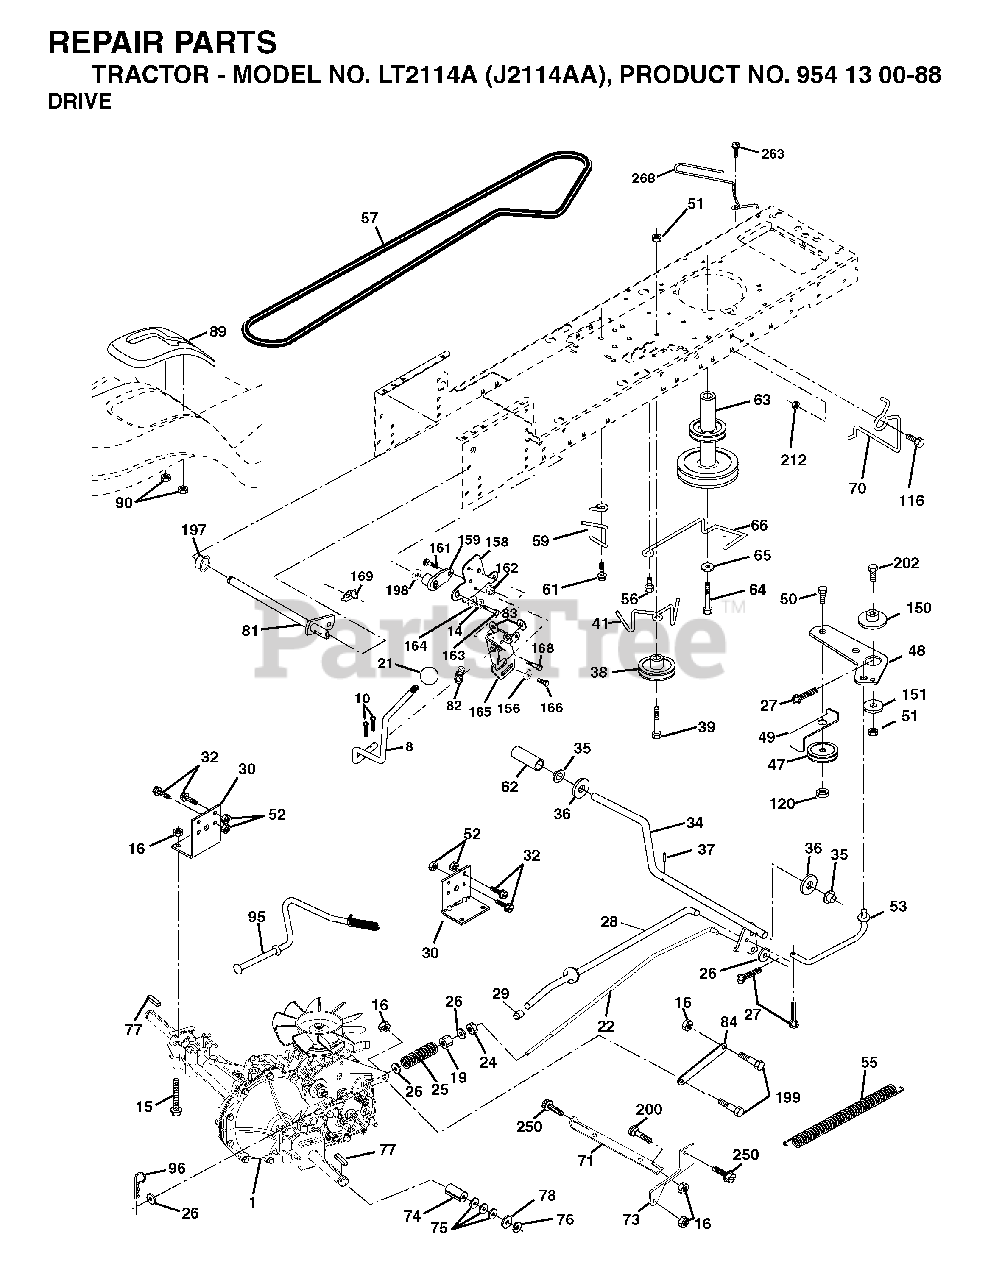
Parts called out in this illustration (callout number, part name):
8	ROD SHIFT FENDER ADJUST STLT
10	PIN COTTER
14	LOCKWASHER
15	BOLT HEX 5/16-18 GR 5
16	NUT.71038.31-18.HEX.NYLOCK
19	NUT
21	KNOB.DUCKHEAD.1/2
22	ROD BRAKE HYDRO
24	NUT
25	SPRING ROD LT
27	COTTER PIN
28	ROD, PARKING BRAKE
29	PLUNGER CAP
30	BRKT, MOUNT TRNSAXLE
32	BOLT
34	SHAFT, FOOT PEDAL
35	BEARING.NYLON
36	WASHER LT
37	DRIVE PIN
38	PULLEY IDLER COMPOSITE
39	BOLT
41	KEEPER, BELT IDLER
47	IDLER PULLEY
48	BELLCRANK, CLUTCH
49	RETAIN BELT
50	BOLT.3/8-16X1.50
51	LOCKNUT
52	LOCKNUT
53	LINK, CLUTCH LT
55	SPRING, RETURN LT
56	SCREW.3/8-16
57	DRIVE BELT, LTH & YTH TRACTORS
59	KEEPER, BELT CENTER
61	SCREW 3/8-16X.875
62	PEDAL COVER T
64	BOLT
65	LOCKWASHER
66	KEEPER BELT ENGINE
71	STRAP TORQUE LH HYDRO
73	STRAP TORQUE RH HYDRO
74	SPACER AXLE
76	E-RING LT
77	SQUARE KEY
81	SHAFT ASM CROSS TAPERED
82	SHIFT SPRING
83	WASHER
95	CONTROL ASM. BYPASS HYDRO
96	RETAINER M
103	NUT.HEX.1/2-20
116	BOLT D
120	NUT LOCK FLG 3/8-16 UNC
150	SPACER, RETAINER
151	WASHER 12/32X2X10GA
156	WASHER.SRRTD.5/16
158	BRACKET
159	HUB
161	BOLT
162	NUT.CROWNLOCK.1/4
165	RP BRACKET
168	BOLT.SHOULDER.5/16-18X
169	PLATE.FASTENING.CROSS.SHAFT
197	NYLINER SNAP 5/8" ID
198	WASHER.NYL.7/8IDX.105"HYD CR
199	BOLT SHOULDER 5/16-18 UNC
200	BOLT
202	BOLT
205	WASHER
212	NUT
250	SCREW 3/8-16X3/4
263	SCREW, 3/8-16X3/4
